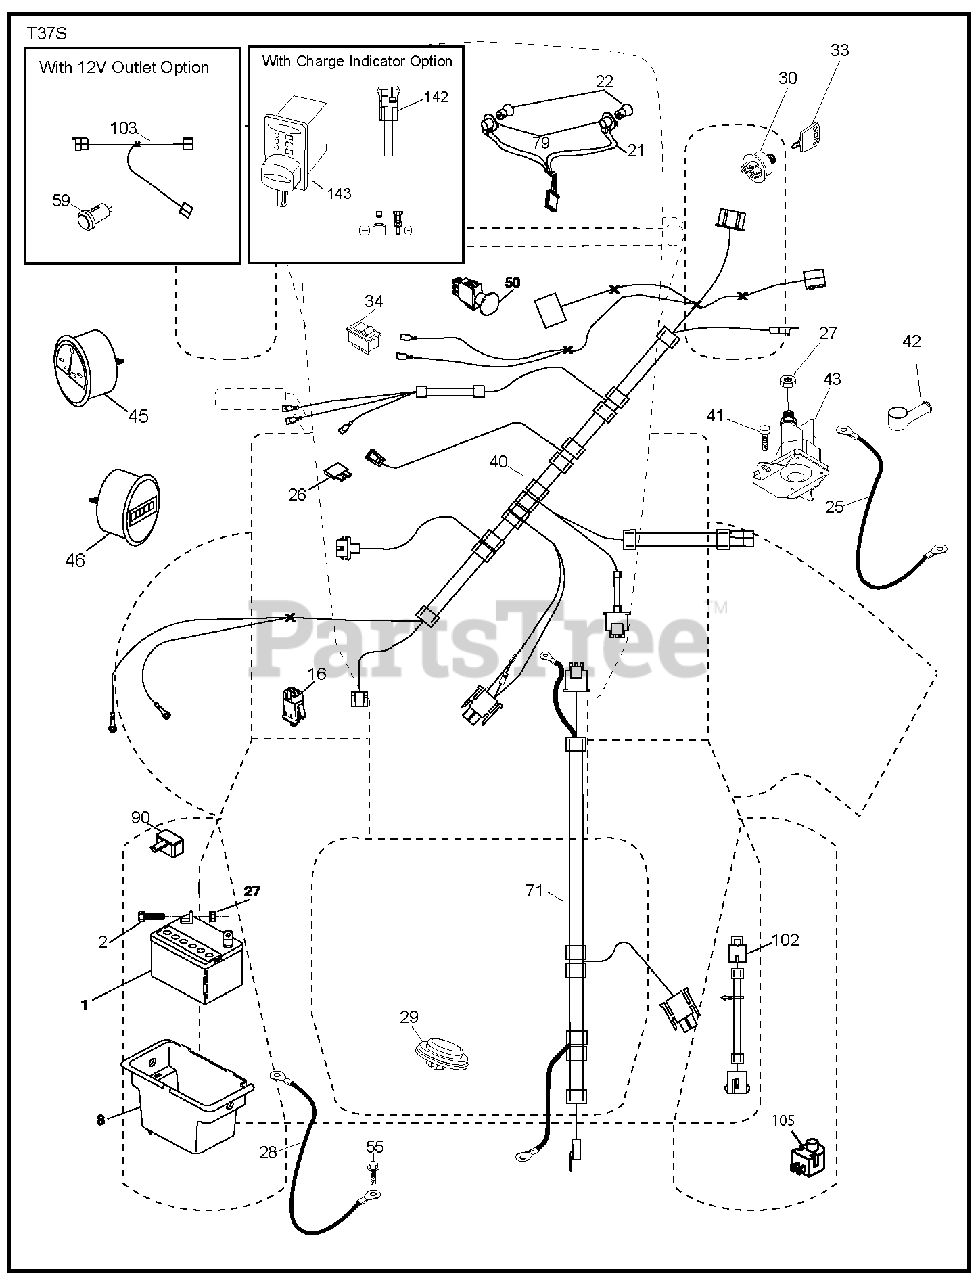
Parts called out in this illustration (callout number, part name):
1	Battery, Dry 30 Amp
2	BOLT.HEX.1/4.X.3/4.DICHROMATE
8	BOX.BATTERY.MNT.REAR.L
16	SWITCH INTERLOOK PUSH-IN
21	HARNESS.LIGHT W/4152J BULBS
25	CABLE.STARTER.6G.BL/RED.17.5
26	FUSE 20AMP
27	NUT
28	CABLE.BLACK.18"REAR.BA
29	SWITCH.SEAT.DELTA.OPC.
30	SWITCH.IGN.DELTA.W.LGH.ROS
33	KEY.CHAIN.BLISTER.PACK.GEN.INT
40	HARNESS IGN. DASH
41	SCREW
42	TERMINAL COVER
43	SOLENOID.W/BRASS.PLUNGER
45	AMMETER GAUGE ROUND SNAP-IN
46	HOURMETER.GAUGE.RNK.SNAPIN.LS
50	RB PTO.SWITCH.8 TERMINAL.BLACK
55	SCREW 5/16"
59	OUTLET.12-VOLT
71	HARNESS.IGN.CHASS.TEX.REAR.BAT
79	BULB HOLDER ASM.
90	COVER.TERMINAL.BATTERY
102	HARNESS PIGTAIL PCH TEX ROS
103	HARNESS.PIGTAIL.12V.OUTLET.
105	REVERSE SWITCH
